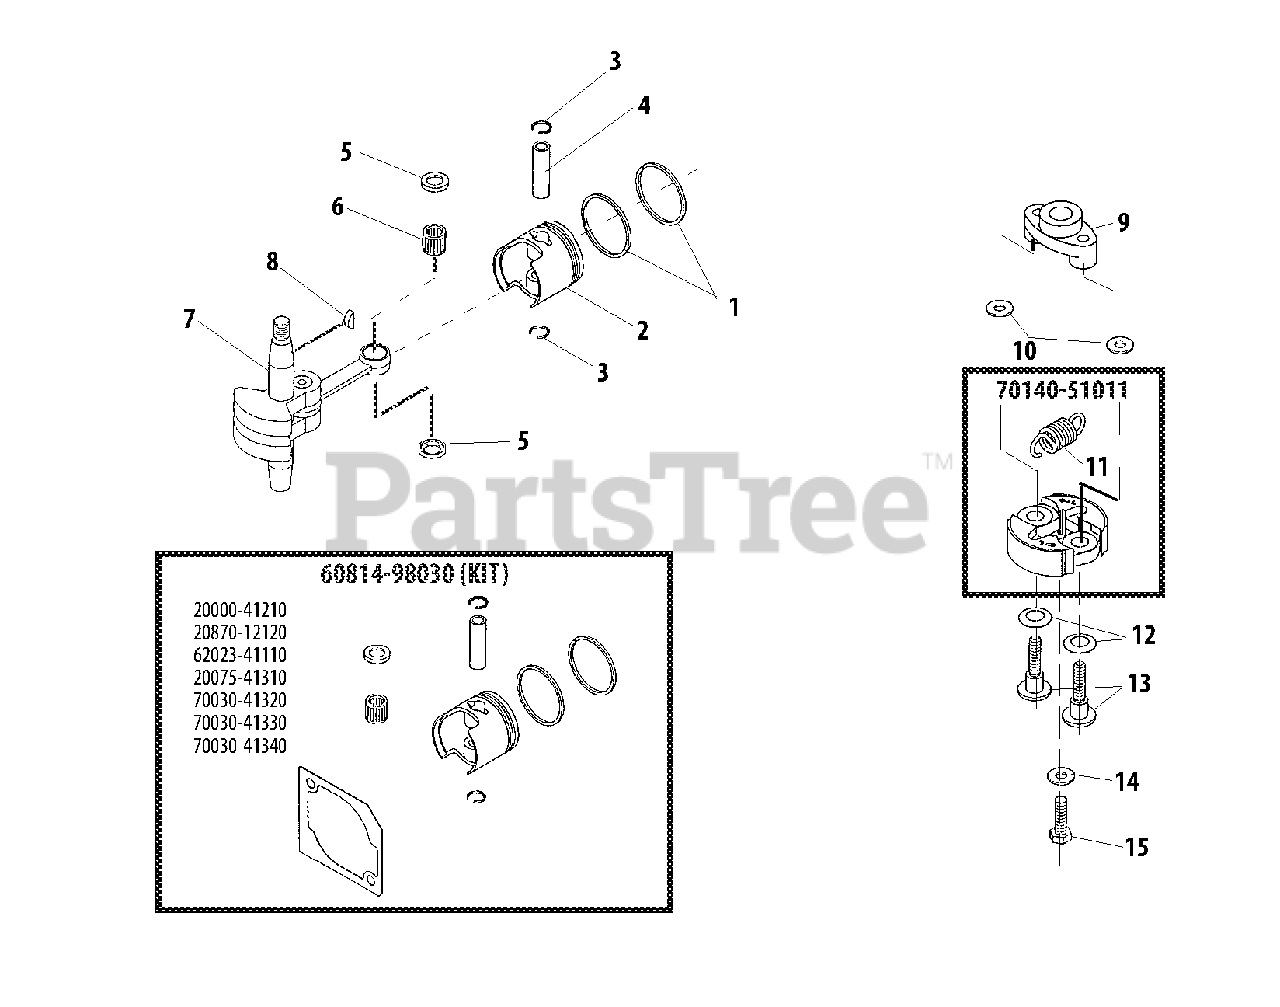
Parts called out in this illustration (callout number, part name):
1	RING, PISTON
2	PISTON
3	RING, RETAINING
3	GASKET, CYLINDER
4	PIN, PISTON
5	WASHER, THRUST
6	BEARING, NEEDLE
7	CRANKSHAFT ASSY
8	KEY - 3X10
9	HUB, CLUTCH
10	WASHER - 6
11	SPRING, CLUTCH
12	WASHER - SPRING
13	BOLT, CLUTCH
14	WASHER - 6
15	SCREW - 6X18
60814-98030	PISTON ASSY
70140-51011	CLUTCH SHOE ASSY
